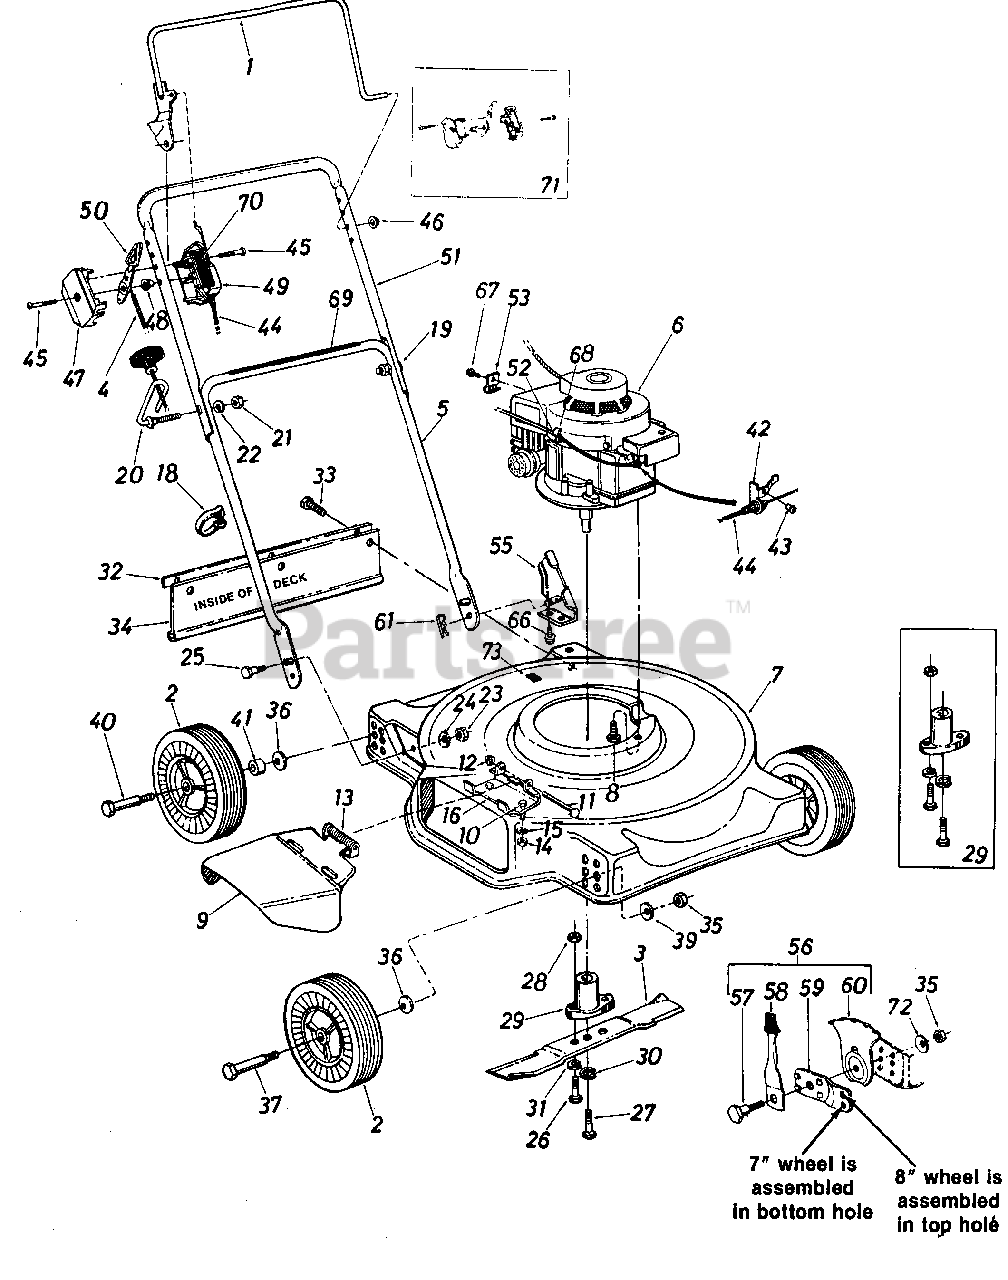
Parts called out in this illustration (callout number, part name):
1	Control Handle Ass'y.-R.H.
2	Wheel Ass'y. Comp.
3	20" Blade
4	Throttle Control Wire-39"
5	Lower Handle (Chrome)
6	Engine
7	20" Deck Ass'y.
8	Hex Wash. Hd. TT-Tap Scr. 3/8-16 x 1.00" Lg
9	Chute Deflector Ass'y.
10	Hex Bolt 1/4-20 x .50" Lg.*
11	Hinge Pin 1/4" Dia. x 3.88 Lg.
12	Push Cap .25" Rod
13	Torsion Spring
14	Hex Nut 1/4-20 Thd.*
15	L-Wash. 1/4" I.D.*
16	Deflector Hinge Plate
18	Cable Tie
19	Curved Carriage Bolt 5/16-18 x 1.38" Lg.
20	Rope Guide Bolt
21	Hex Nut 5/16-18 Thd.*
22	L-Wash. 5/16" I.D.*
23	Hex Ins. L-Nut 5/16-18 Thd.
24	Bell-Wash. .345" I.D. x .88" O.D.
25	Shld. Bolt .437" Dia. x .268
26	Hex Bolt 5/16-24 x 1.00" Lg. (Grade 5)
27	Hex Bolt 3/8-24 x 2.25" Lg. (Grade 5)
28	Hex Nut 5/16-24 Thd.*
29	Blade Adapter Kit
30	L-Wash. 3/8" I.D.-H.D.
31	L-Wash. 5/16" I.D.*
32	Retainer Strip
33	Hex Wash. Hd. AB-Tap Scr. 1/4" x .62" Lg.
34	Rear Flap Ass'y.
35	Hex Nut 3/8-16 Thd.*
36	Bell-Wash. .400" I.D. x .88"
37	Front Axle Bolt
39	Bell-Wash. .39" I.D. x 1.13" O.D.
40	Rear Axle Bolt
41	Spacer .511 I.D. x .70" O.D.
42	Cable Bracket
43	Pop Rivet .156" Dia. x .379
44	43" Control Cable-Yellow
45	Truss Mach. Scr. #12 x 1.50"
46	Cap Speed Nut 5/16" Rod
47	Control Panel Half
48	Control Disc Pin
49	Clutch Panel Half
50	Throttle Control Lever
51	Upper Handle (Chrome)
52	Hex "B" Tap Scr. #10 x .38"
53	Casing Clamp
55	Handle Mount Brkt. Ass'y.-L.H.
56	Height Adjuster Ass'y.-Comp.-R.H.
57	Shoulder Bolt .500" Dia. x .357
58	Spring Lever Ass'y. w/Knob
59	Pivot Bar
60	Index Plate
61	Hairpin Cotter
66	Hex Wash. Hd. Self-Tap Scr. 5/16-18 x .50" Lg.
67	Hex Wash. Hd. AB-Tap Scr. #8 x .38" Lg.
68	Cable Clip
69	Instruction Label-Handle
70	Control Label-Throttle
71	Kit-Control Housing Comp.
72	Belleville Wash. .39 I.D. x 1.4 O.D.
73	Plastic Plug
